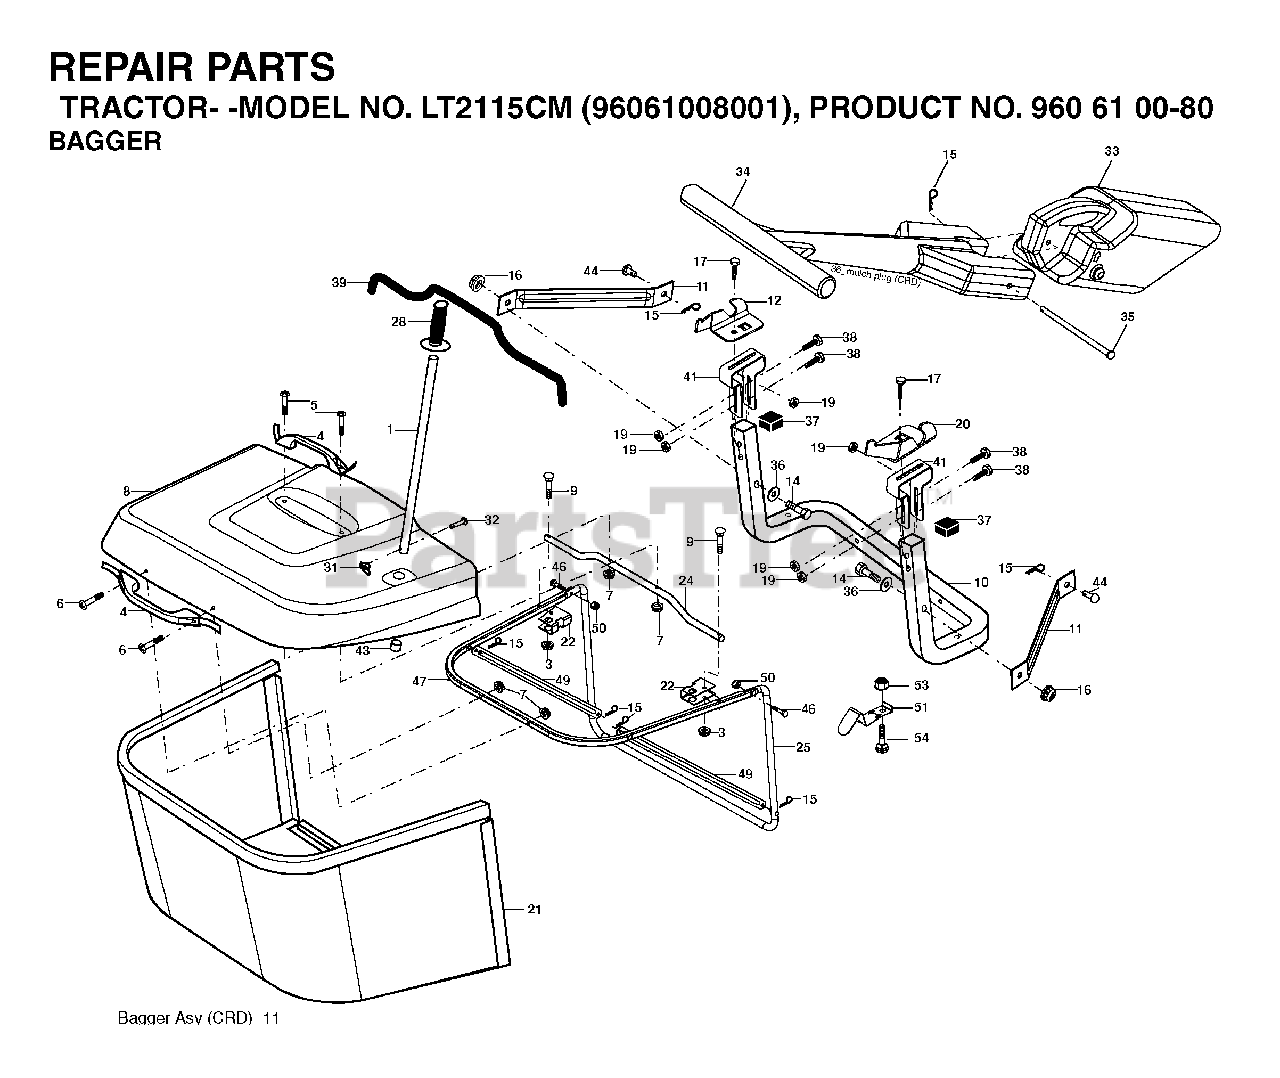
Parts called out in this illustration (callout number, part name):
1	TUBE HANDLE
3	NUT T
5	SCREW.PAN.HEAD
11	BRACKET
14	BOLT-HEX EAK
15	RETAINER-SPRNG RB
16	NUT LOCK FLG 3/8-16 UNC
17	BOLT
19	NUT LOCK HEX FLANGE 5/16-18
20	BRKT.PIVOT.RH.CRD
22	BRACKET
24	TUBE
28	GRIP.HANDLE.BLACK
31	RETAINER CLIP
32	RIVET,DRILLED
33	PLUG
35	PIN
38	BOLT.5/16-18X2.5
41	BRKT, BAGGER
43	PLUG, TUBING END
46	BOLT.CARRIAGE.5/16-18
50	NUT.71038.31-18.HEX.NYLOCK
53	NUT
54	BOLT
